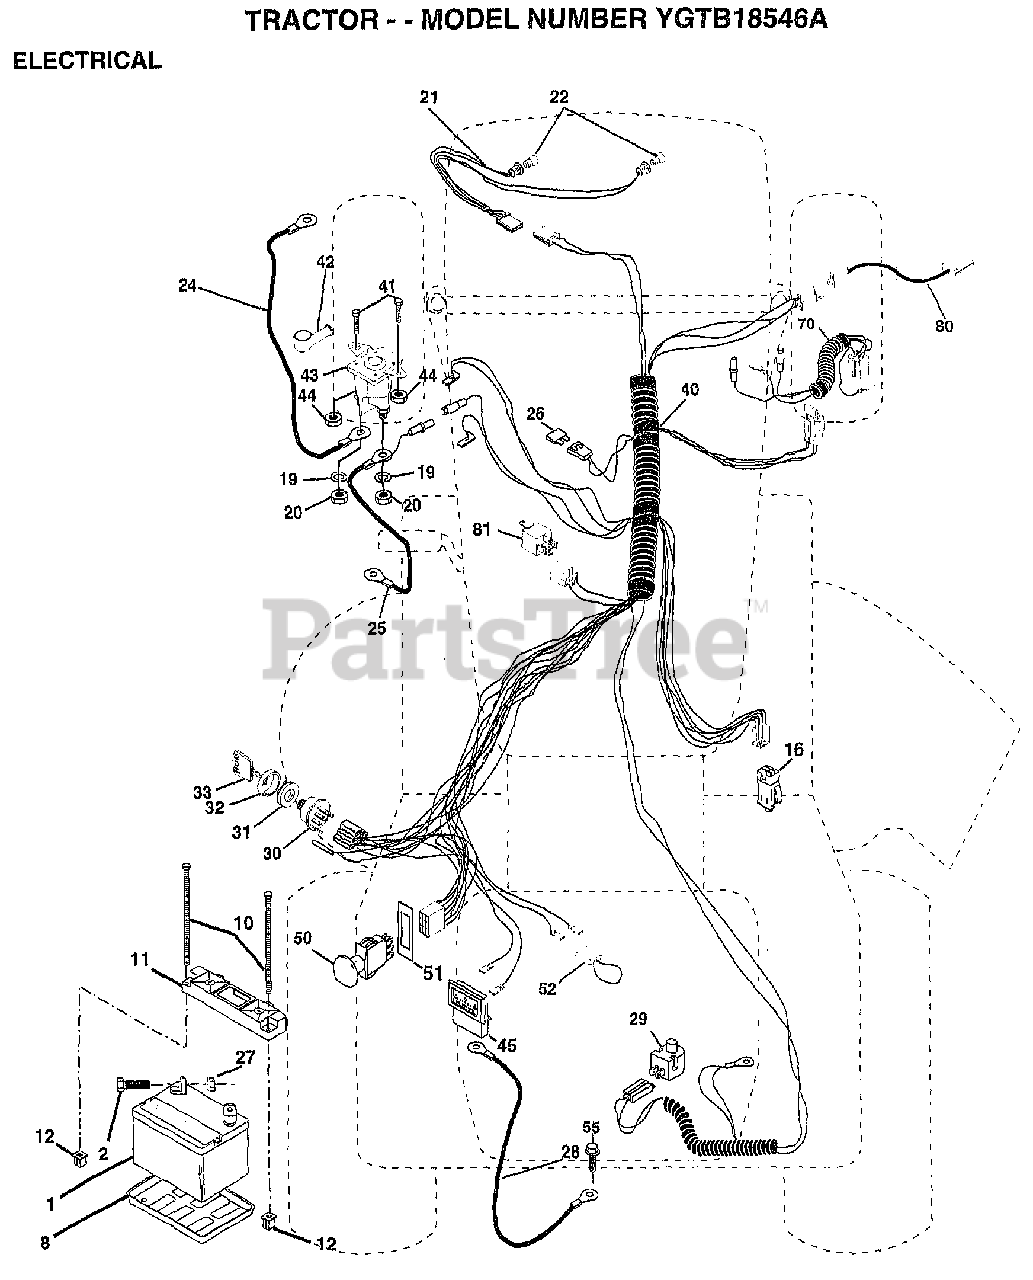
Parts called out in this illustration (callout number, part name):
2	BOLT LT
8	"TRAY T, BATTERY"
11	HOLDDOWN BATTERY
16	SWITCH INTERLOCK
20	NUT
21	HARNESS.ASM.LIGHT W/4152J
22	HEADLAMP BULB
24	"CABLE T, BATTERY"
25	CABLE.6GA.22W/16W
26	FUSE.15 AMP
27	NUT
28	CABLE.GRND.6GA.21
29	SWITCH.PLUNGER
30	SWITCH IGN 4POS
31	NUT IGNITION
32	COVER KEY SWITCH
33	KEY
40	HARNESS.IGNITION
41	BOLT HXHD FIN
44	NUT HXKEP 1/4X20
45	AMMETER
50	PTO SWITCH.BLK
51	RING RETAIN PTO
52	PROTECTION LOOP
55	SCREW LT
70	HARNESS.ENGINE
80	HARNESS.CLUT.EVX.
81	RELAY ASSY T
